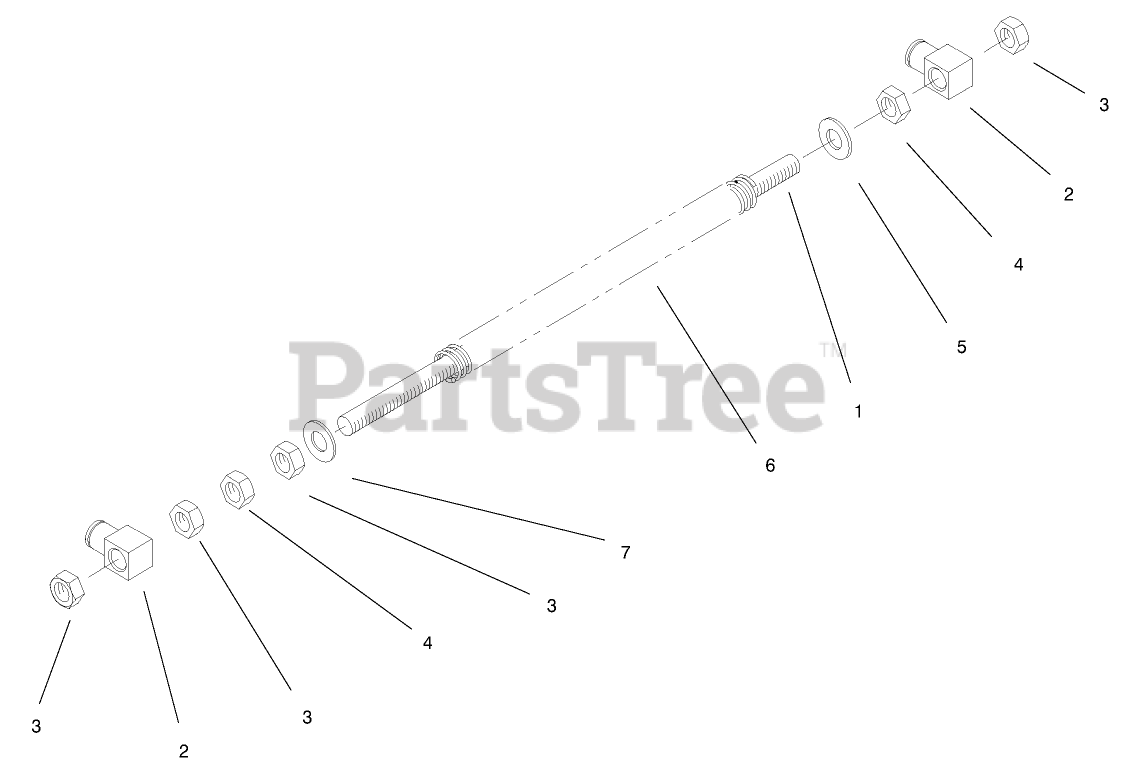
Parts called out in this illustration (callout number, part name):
1	ROD-LIFT, DECK
2	SWIVEL-DECK MOUNT, REAR
3	NUT-HEX
4	NUT-JAM
5	Washer
6	SPRING-COMPRESSION
7	WASHER-FLAT
